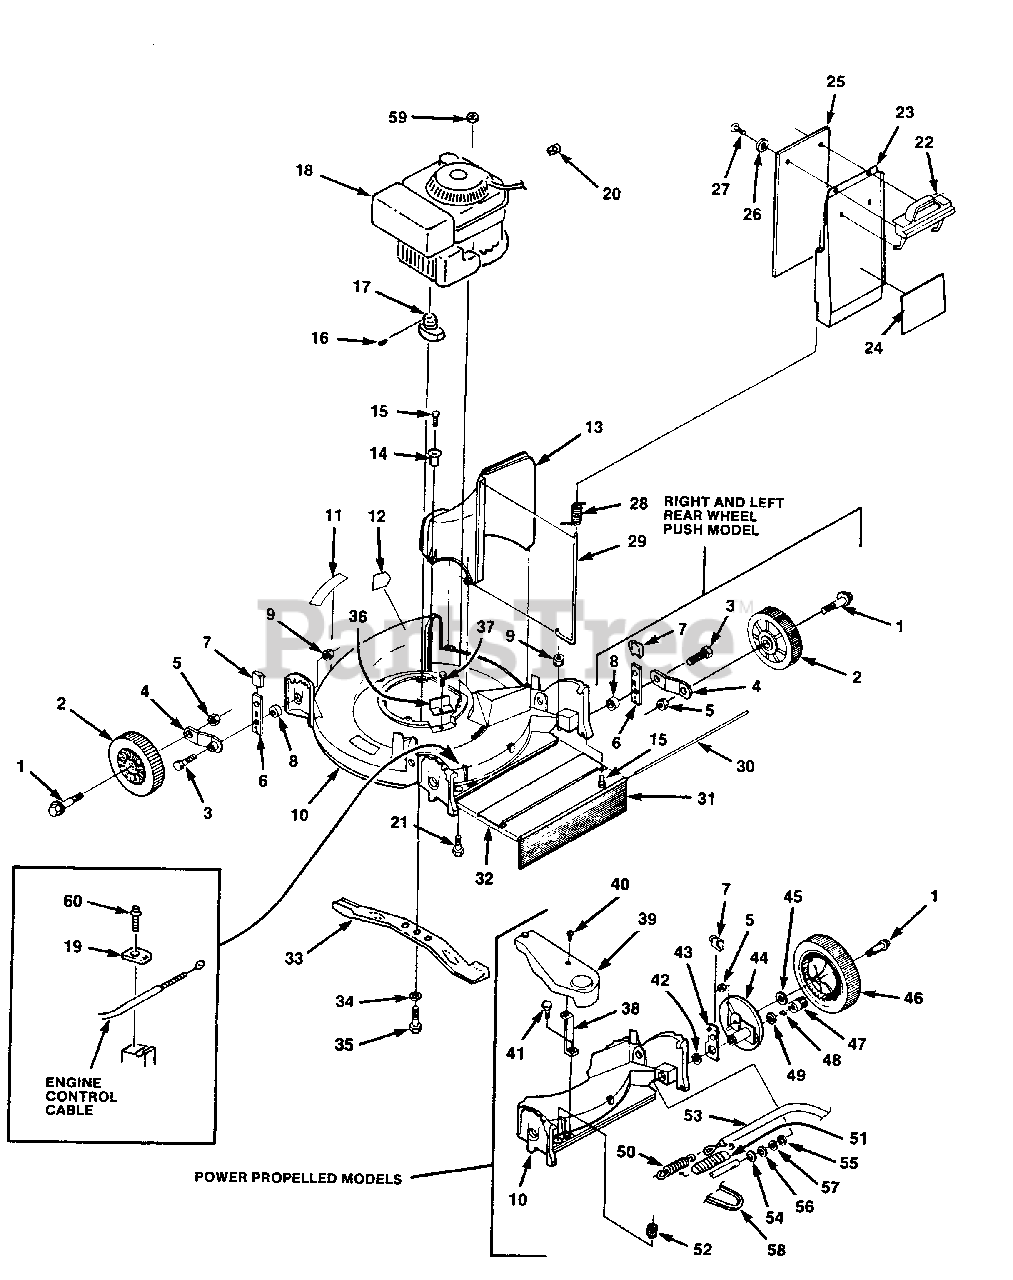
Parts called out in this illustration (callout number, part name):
1	BOLT- Axle
2	WHEEL & TIRE
3	BOLT- Hex hd. 5/16-18
4	ARM- Wheel hgt. adj.
5	NUT- Hex 3/8-24
6	SPRING- Index
7	KNOB- Indexing spring
8	SPACER- Indexing spring
9	NUT- Flange 5/16-18
10	DECK- 21"
11	DECAL- Product ident.
12	DECAL- Warning
13	CHUTE- Discharge
14	EYELET- Simpson
15	SCREW- Hex hd. (1/4-20 x 3/4")
16	KEY- 5/8 x 5/32"
17	ADAPTER- Blade
18	ENGINE- 4.0 HP, 2 Cycle
20	STOP- Rope
21	SCREW- 5/16-18 x 1"
22	HANDLE- Door
23	DOOR- Chute
24	DECAL- Door
25	DAMP- Flap
26	WASHER- Flat 1/4"
27	SCREW- (Rd. Hd. 1/4-10 x 5/8")
28	SPRING- Door
29	PIN- Hinge
30	ROD- Drap flap
31	FLAP- Drag
32	COVER- Rear
33	BLADE- 21"
34	WASHER- Lock 7/16"
35	BOLT- Shoulder
36	COVER- Belt opening
37	SCREW- (Hex hd. 1/4-20 x 1/2")
38	SUPPORT
39	COVER- Drive
40	SCREW- (Rd. Hd. 1/4-20 x 3/4")
41	SCREW- (Hex hd. 10-16 x 1/2")
42	SPACER- Hgt. Adj.
43	SPRING- Index
44	DRIVE WHEEL SUPPORT
45	WASHER- Flat
46	WHEEL & TIRE (drive)
47	PINION- R.H.
48	PAWL- Pinion
49	WASHER- Flat
50	SPRING- Traction lever
51	COVER- Spring
52	SPRING- Compression
53	CABLE- Traction
54	RING- Eaton
55	WASHER- Flat
56	WASHER
57	WASHER- Shim
58	BELT- Drive
59	NUT- 5/16-18 C'Lock
